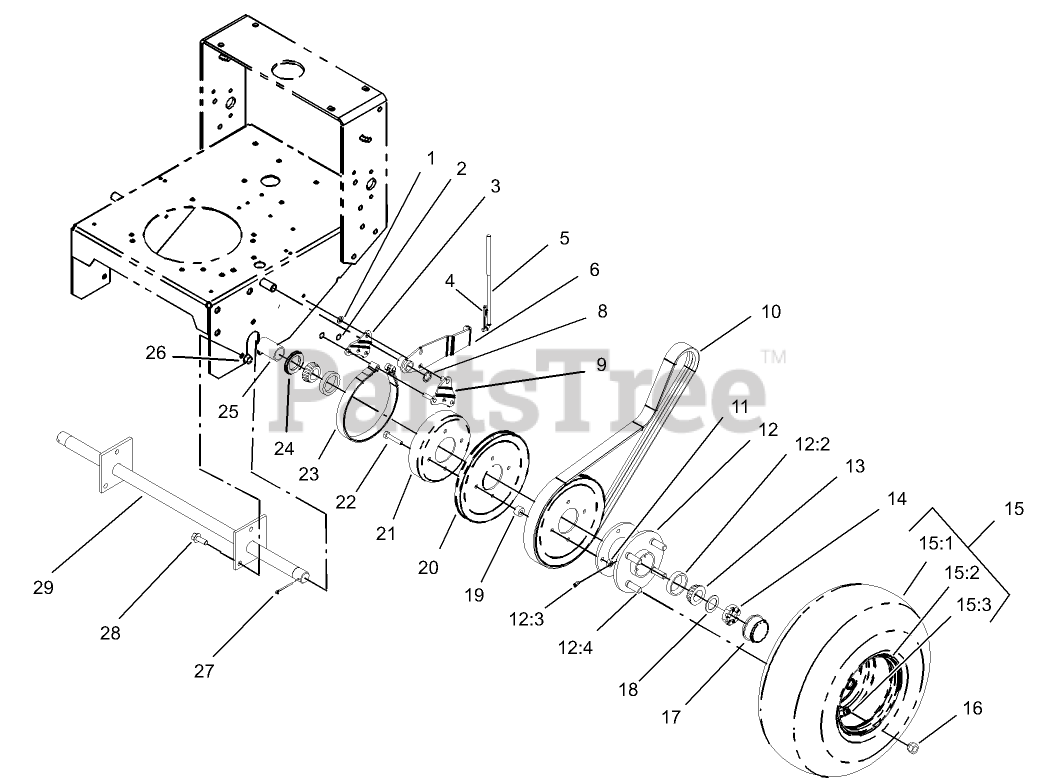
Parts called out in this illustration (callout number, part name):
1	RING-RETAINING, EXTERNAL
2	RING-RETAINING
3	PLATE-LINK, BRAKE
4	PIN-COTTER
5	ROD-BRAKE
6	BRAKE ARM ASM
8	RING-RETAINING
9	BRAKE LINK ASM
10	V-BELT
11	NUT-LOCK, NI
12	HUB/WHEEL ASM
12:2	BEARING-CUP, TAPERED
12:3	FITTING-GREASE
12:4	STUD-WHEEL
13	BEARING-CONE, TAPERED
14	NUT-SHH
15	WHEEL AND TIRE ASM
15:2	WHEEL
15:3	STEM-VALVE
16	NUT-LUG
17	CAP-DUST
18	WASHER-SPACER
19	SPACER-PULLEY
20	PULLEY-WHEEL
21	DRUM-BRAKE
22	SCREW-HH
23	BAND-BRAKE
24	SEAL-GREASE
25	SPACER-WHEEL
26	NUT-HF
27	PIN-COTTER
28	SCREW-HHF
29	AXLE ASM
